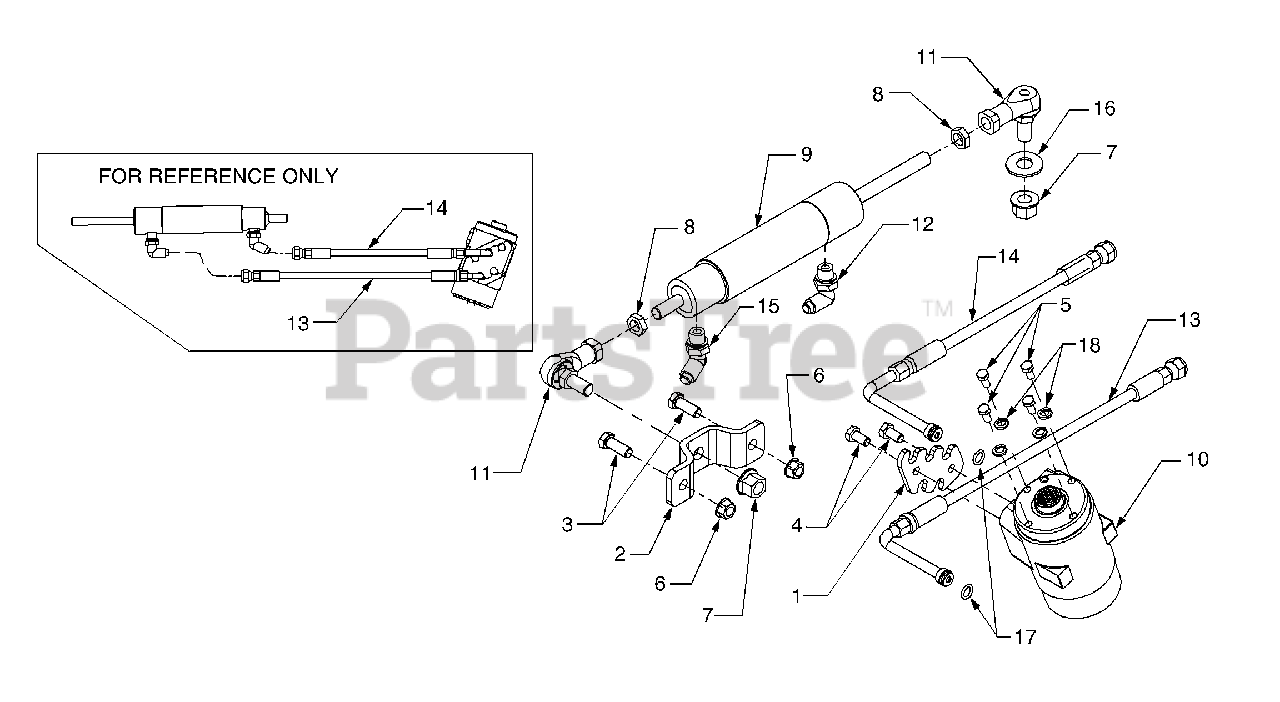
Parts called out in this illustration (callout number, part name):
1	Plate, Steering Pump Port
2	Bracket, Cylinder Mounting
3	Screw, Hex Cap 3/8-16 x 1.0 GR5
4	Screw, Hex Cap M8-1.25 x 16MM GR5
5	Screw, Hex Cap, M6 x 14MM
6	Nut, Hex Flange Lock, 3/8-16
7	Nut, Hex Flange Lock, M12 x 1.75
8	Nut, Hex, M12 x 1.75 RH
9	Cylinder, Steering
10	Pump, Hydraulic Steering
11	Ball Joint, 12MM x 1.75 RH
12	Fitting, 90 Degree Elbow
13	Hose, Front Steering
14	Hose, Rear Steering
15	Fitting, 45 Degree
16	Washer, Flat, .51 x 1.12 x .060
17	O-Ring, .426 x .566 x .070
18	Washer, Lock, 1/4"
